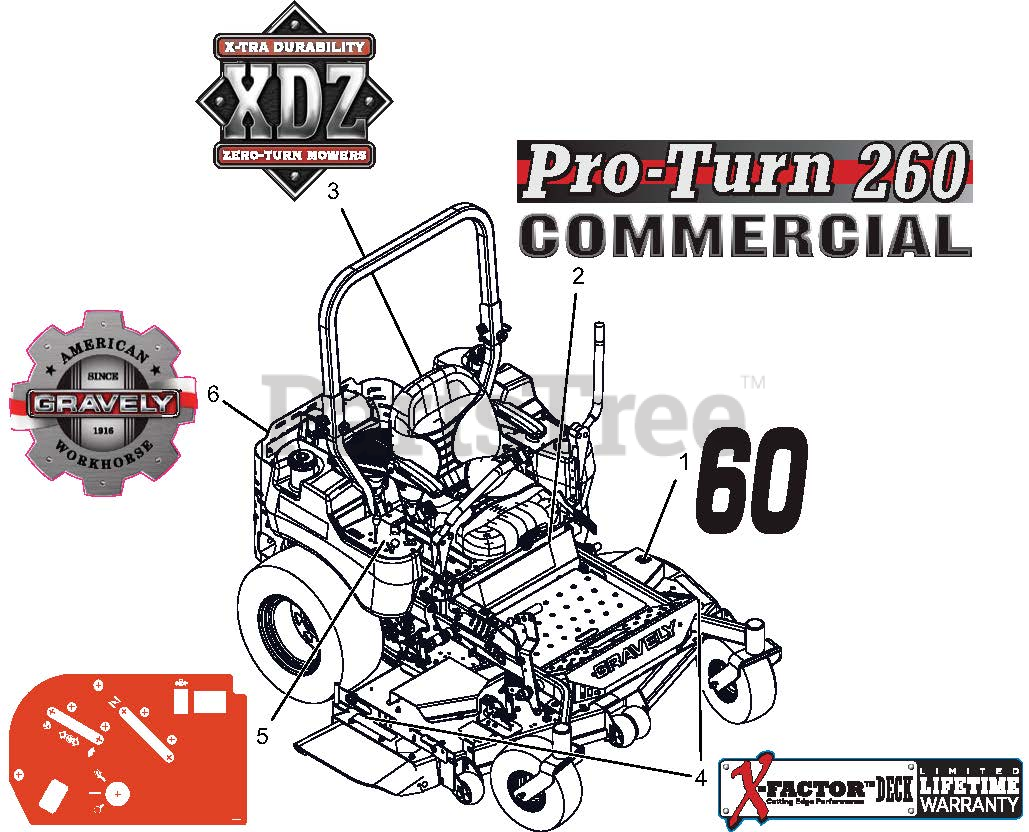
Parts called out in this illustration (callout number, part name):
1	DECAL, 60"
2	DECAL, PROTURN 260
3	DECAL, XDZ
4	DECAL, X-FACTOR DECK
5	DECAL, CONTROL PANEL NON-EFI
6	DECAL, GRAVELY HERITAGE-LARGE
